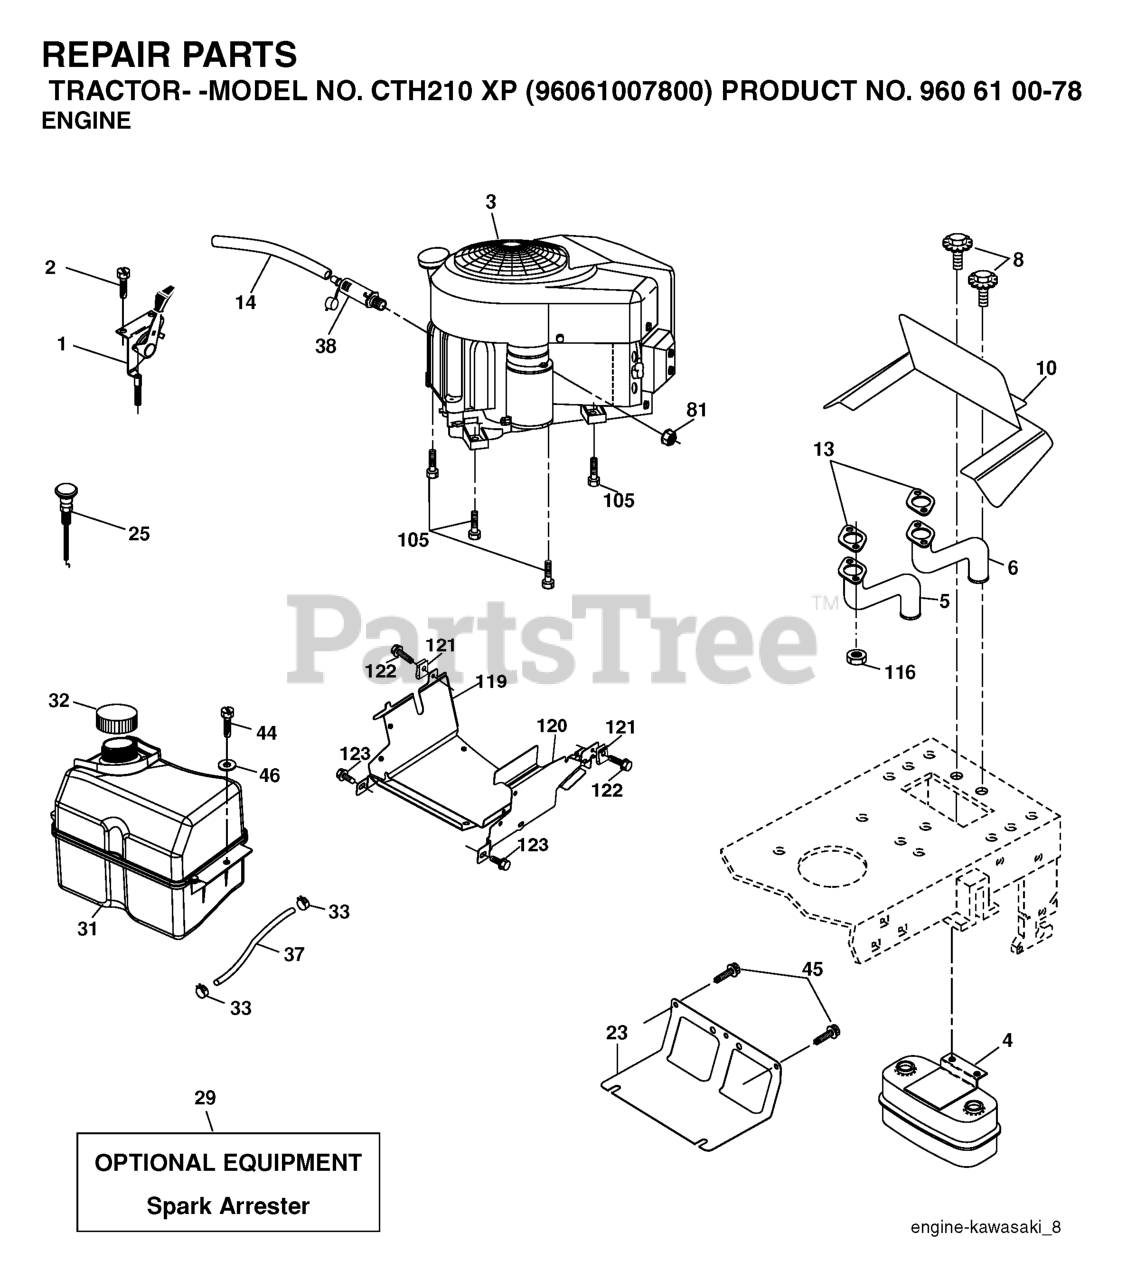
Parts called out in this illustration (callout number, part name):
2	SCREW
4	MUFFLER.TWIN.CYL.LOW.TONE
5	TUBE EXHAUST LH
6	EXHAUST.TUBE.RH.KAWA
8	BOLT.5/16-18UNCX3/4 W/SEMS.BLK
10	RP SHIELD HEAT MUFFLER
14	TUBE, DRAIN OIL ASM.
23	SHIELD.BROWNING.DBR.GUARD
25	CONTROL, CHOKE, 37", PUSH
29	KIT.SPARK ARRESTOR 794945 B&S
31	TANK FUEL
32	FUEL CAP
33	HOSE CLAMP
37	LINE.FUEL.20
44	SCREW HEXWSHR 1/4-20X3/4
45	SCREW, 3/8-16X3/4
81	NUT
105	SCREW 3/8-16X1
116	NUT.HEX.FLANGE.TOPLOCK
